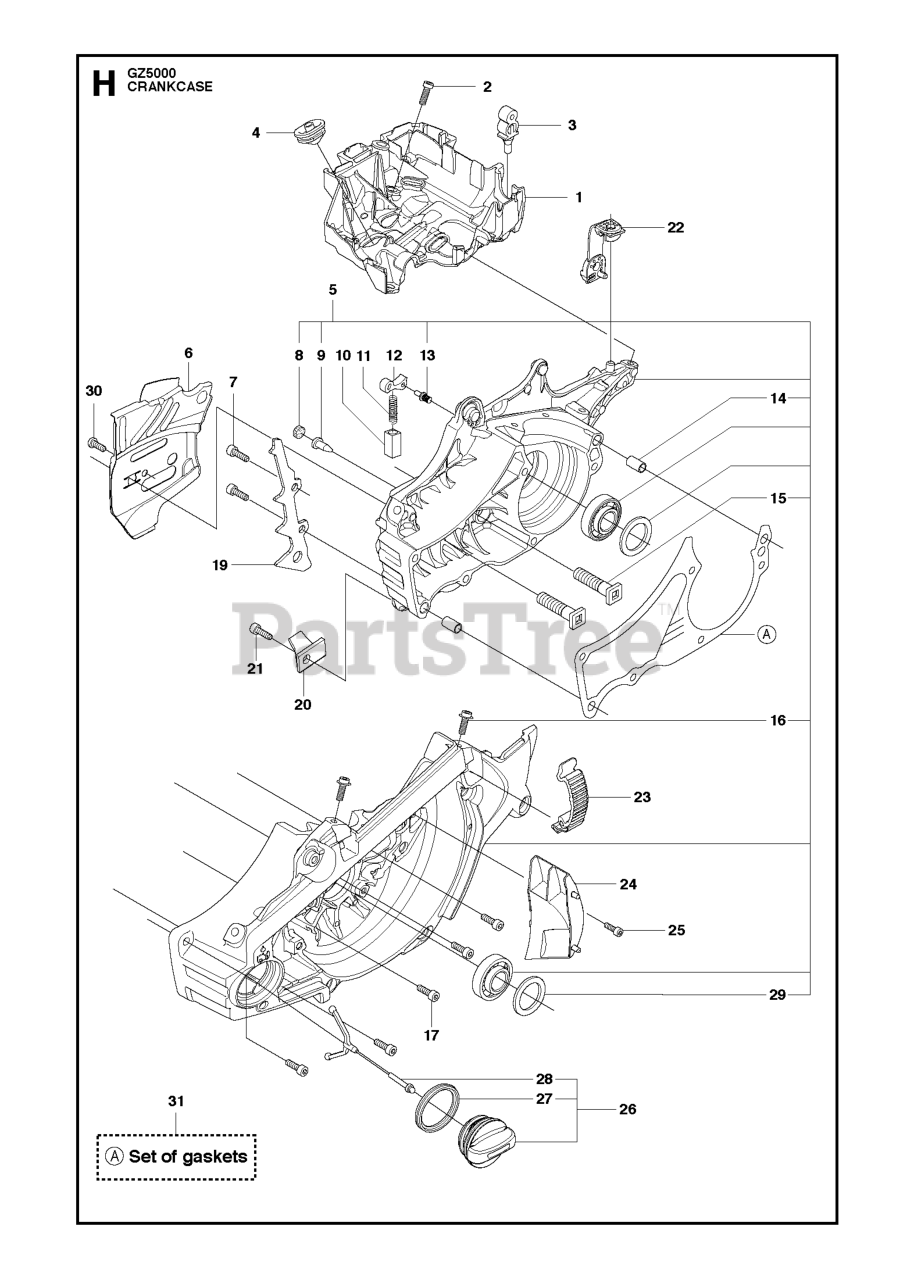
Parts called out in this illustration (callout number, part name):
1	CARBURETTOR AREA BASE ASSY
2	SCREW ITXSCFM
3	CARBURETOR MOUNTING
5	CRANKCASE ASSY
6	CHAIN GUIDE PLATE
7	SCREW ITXPANM M5X16 T27 10.9
8	FILTER
9	VALVE-CHECK (DUCKBILL)
10	SPRING GUIDE
11	POSITION SPRING
14	GUIDE BUSHING
15	BAR BOLT
16	SCREW ITXSCM WASHER M5X12 T27
17	SCREW ITXSCM M5X25 12.9 TBO T
20	CHAIN CATCHER
22	DEFLECTION LIMITER
24	AIR NOZZLE
25	SCREW ITXSCM M4X15 T27 12.9 T
26	TANK CAP ASSY
27	GASKET TANK CAP
29	RADIAL SEAL
30	SCREW CITXPANT
31	GASKET KIT 50CC
